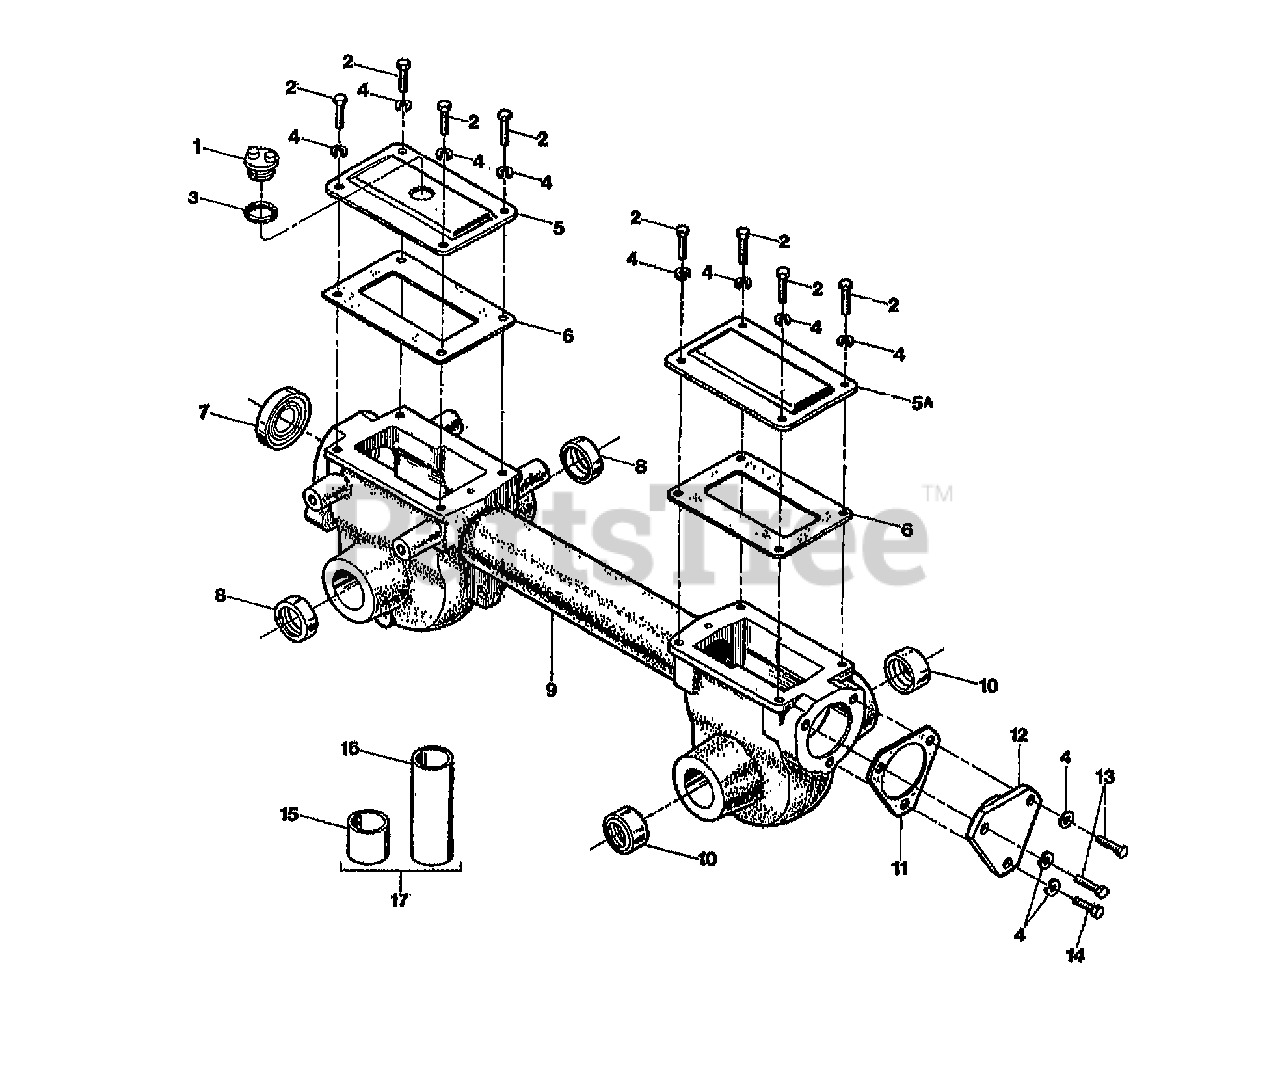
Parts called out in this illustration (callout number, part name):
1	PLUG-OIL FILL 3/4-10
2	SCR-HH 5/16-18X.5 GD5 YEL
3	GASKET-O RING .674 I.D.
4	WASHER-LK .312 ZP
5	COVER-TRANS FRNT PNT
5A	CVR-TRANS REAR PNT
6	GASKET-GEAR HSG
7	SEAL-OIL DRIVESHAFT
8	SEAL-OIL WHEELSHAFT
9	TRANSMISSION-MACH
10	KIT-OIL SEAL TUFFY
11	GASKET-BEARING CAP .010
11	GASKET-BEARING CAP .030
12	CAP-REAR BEARING-PM
13	SCR-HH 5/16-18X1.0 G5 ZP
14	SCR-HHC 5/16-18X.75 GR 5 ZP
15	SEAL-DRIVER PILOT
16	DRIVER-PLASTIC
17	KIT-DRIVER
